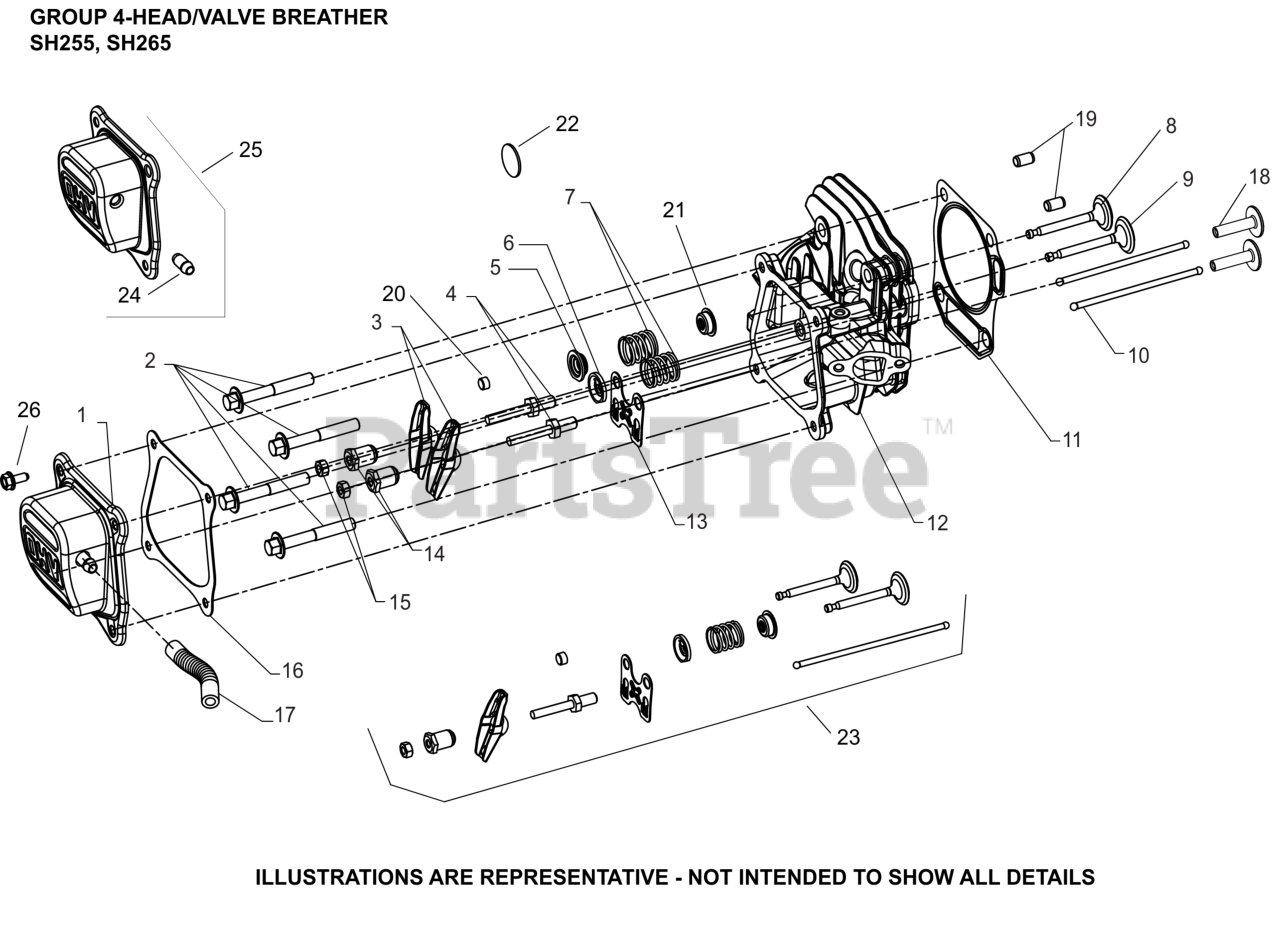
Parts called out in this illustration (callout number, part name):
1	COVER, VALVE ASSEMBLY
2	SCREW, HEX FLANGE CYL HEAD
3	ARM, ROCKER
4	STUD, ROCKER ARM-USE 14 072 22-S
6	RETAINER, VALVE SPRING
7	SPRING, VALVE
8	VALVE, EXHAUST
9	VALVE, INTAKE
10	ROD, PUSH-(#1841101S)
11	KIT, HEAD GASKET
12	HEAD ASSEMBLY, CYLINDER
13	PLATE, PUSHROD GUIDE
14	PIVOT, ROCKER ARM
15	NUT, HEX JAM
17	TUBE, BREATHER - (#1812313S)
21	SEAL, VALVE STEM
22	REED, BREATHER
23	KIT, VALVE TRAIN
26	SCREW, HEX FLANGE (M6)-USE 25 086 433-S
